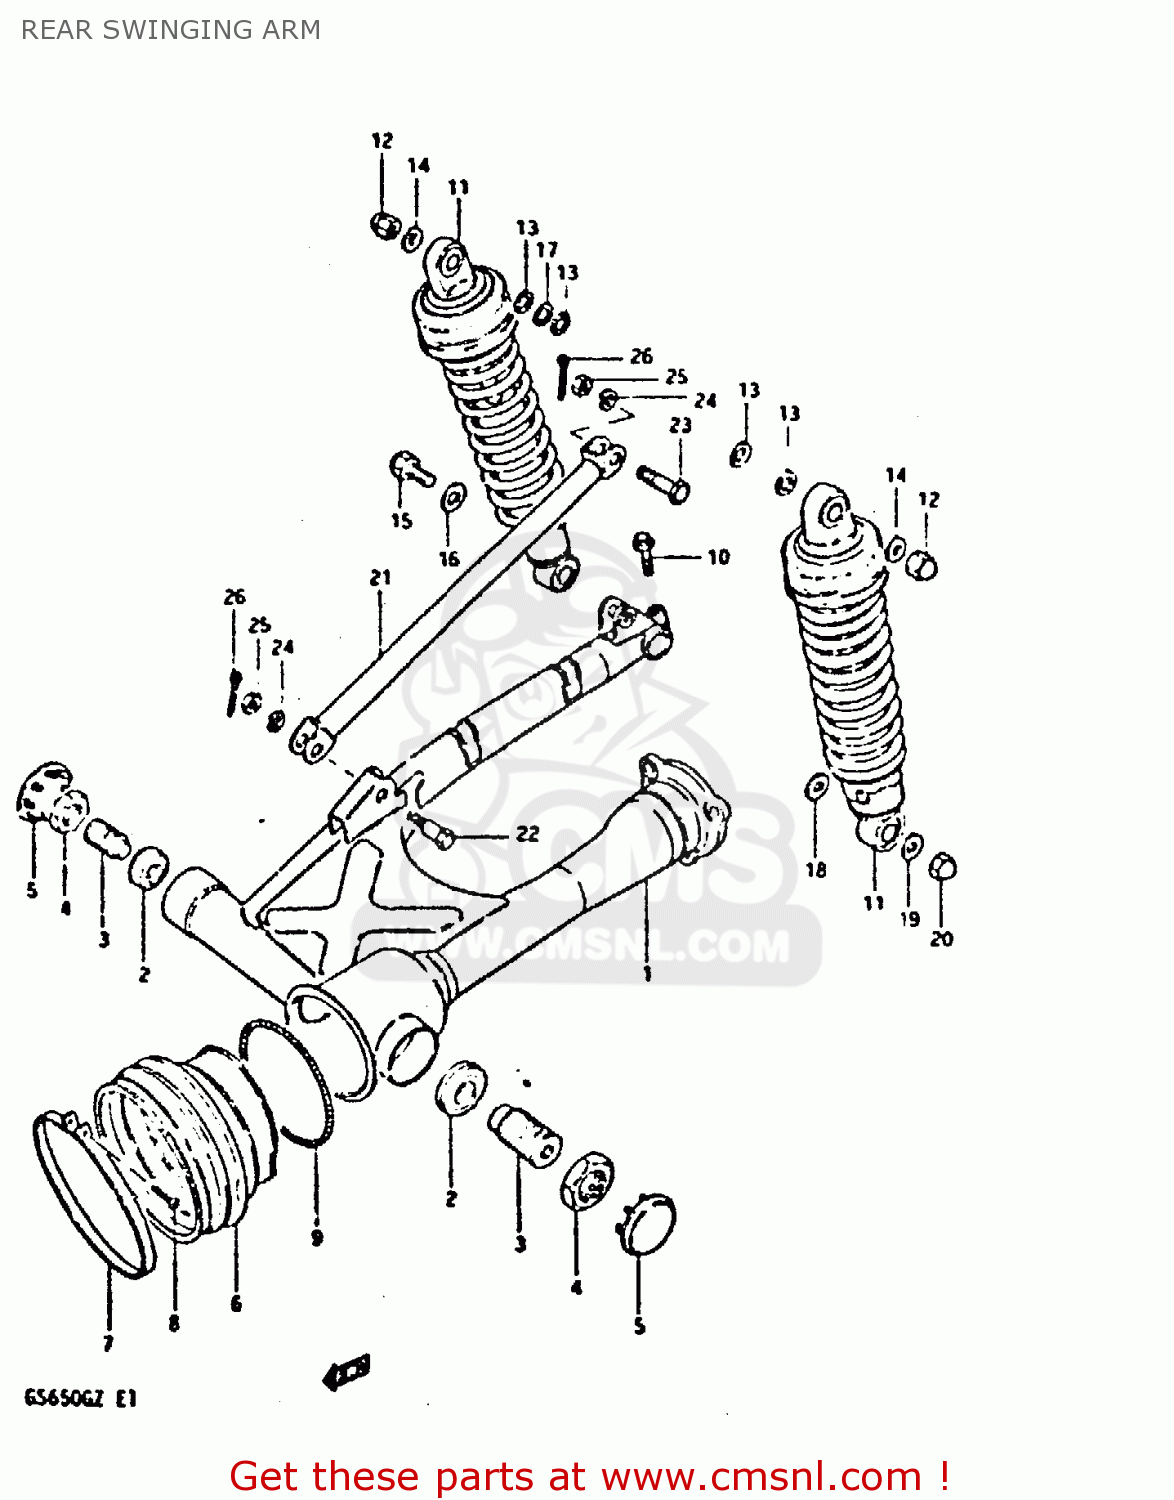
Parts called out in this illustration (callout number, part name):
1	REAR SWINGING ARM SET
2	BEARING(15X35X11.75)
3	BOLT,REAR SWING ARM PIVOT
4	NUT (22MM)
5	CAP,REAR SWING ARM PIVOT
6	BOOT,PROPELLER SHAFT
7	CLAMP
8	SCREW 4X25
9	SPRING,PROPELLER SHAFT
10	BOLT
11	SHOCK ABSORBER, REAR
12	NUT
13	WASHER
14	WASHER
15	BOLT 12X33
16	WASHER (12.5X24X1.6)
17	WASHER (12.5X24X3.2)
18	WASHER
19	WASHER
20	NUT, LOWER LH
21	TORQUE LINK,REAR
22	BOLT
23	BOLT(10X39)
24	WASHER
25	NUT
26	PIN 20X20
